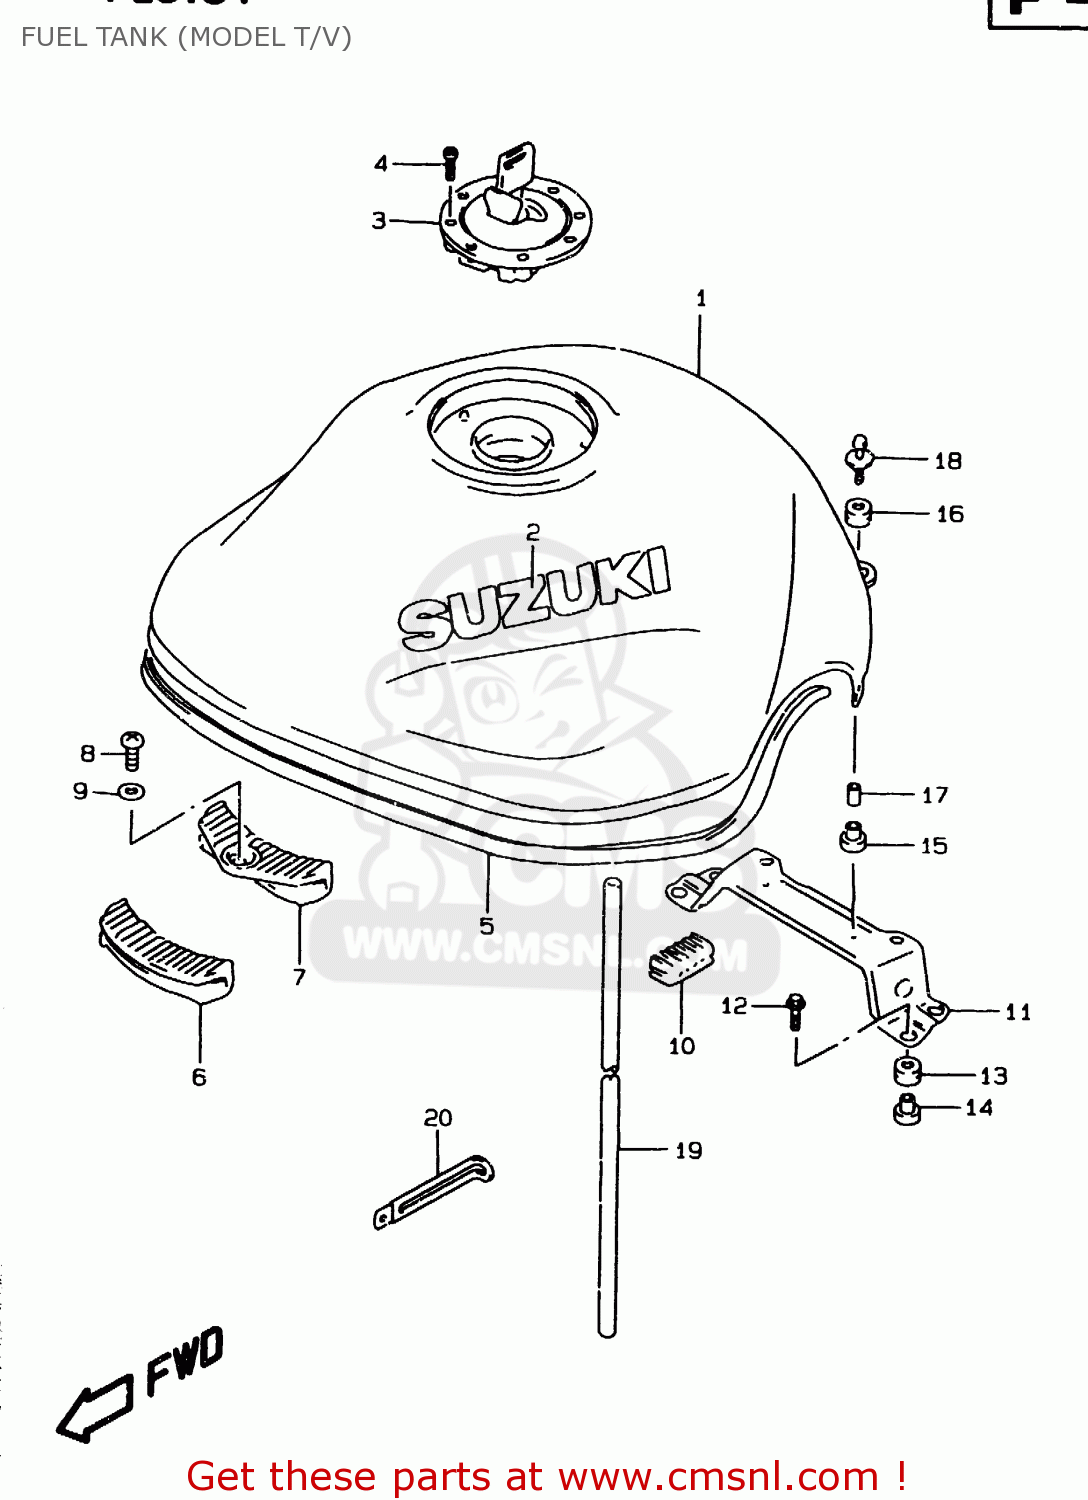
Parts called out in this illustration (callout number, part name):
1	TANK ASSY, FUE
2	EMBLEM,FUEL TANK
3	CAP SET,FUEL TANK
4	BOLT(5X20)
5	MOLDING
6	CUSHION,FUEL TANK FR
7	CUSHION,FUEL TANK FR
8	SCREW
9	WASHER
10	CUSHION,SEAT(40X20X15)
11	BRACKET,FUEL TANK RR
12	BOLT(6X25)
13	CUSHION
14	WASHER
15	CUSHION
16	CUSHION
17	SPACER
18	BOLT(6X30)
19	HOSE(7X10.2X2000)
20	CLAMP(L:97)
